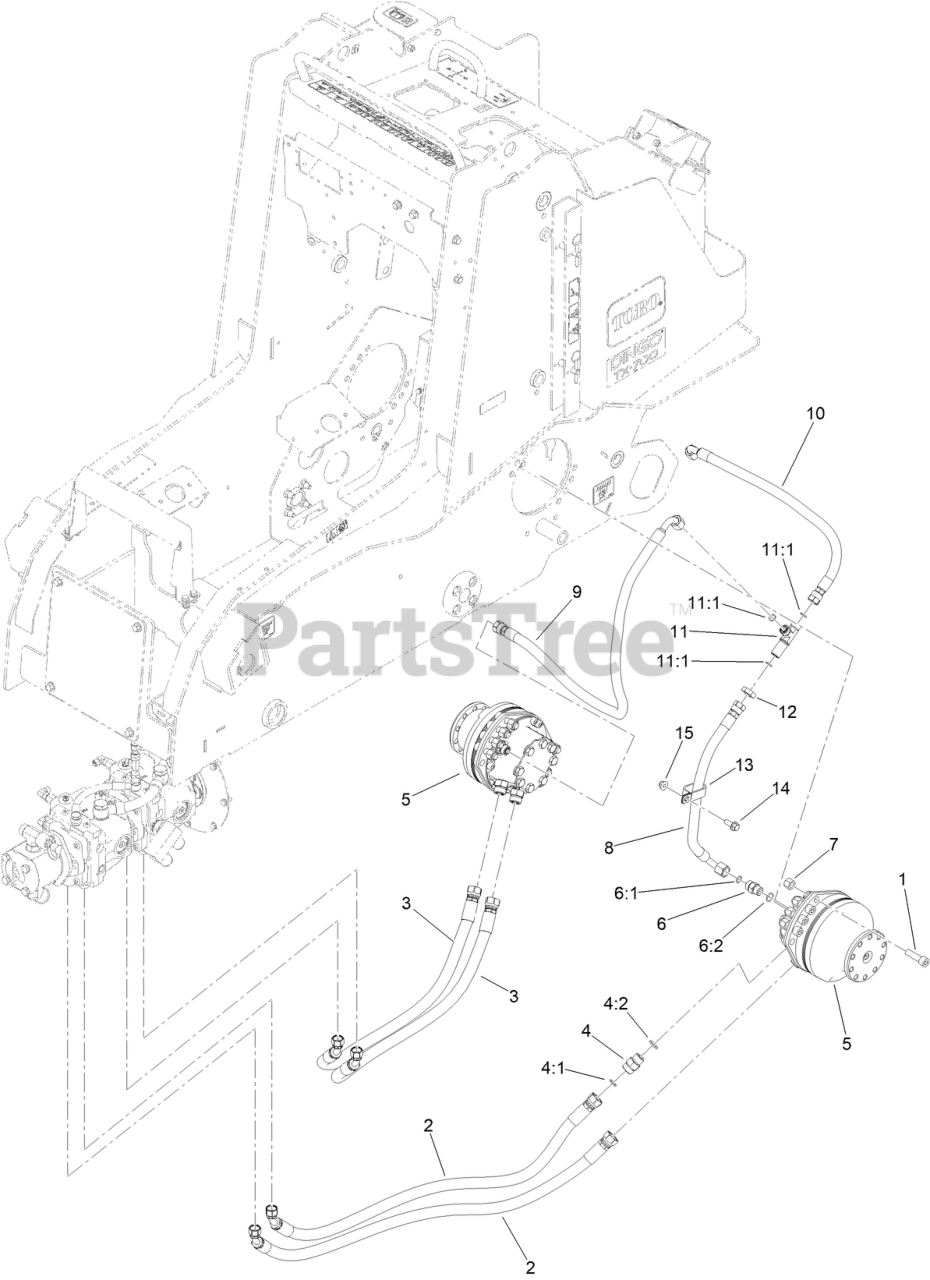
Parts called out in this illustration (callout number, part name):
1	NUT-LOCK, NI
2	HOSE ASM-HYD
3	HOSE ASM-HYD
4	FITTING-STRAIGHT
4:1	O-RING
4:2	O-RING
5	WHEELMOTOR ASM
6	FITTING-STRAIGHT
6:1	O-RING
6:2	O-RING
7	SCREW-HSH
8	HOSE ASM-HYD
9	HOSE ASM-HYD
10	HOSE ASM-HYD
11	FITTING-TEE
11:1	O-RING
12	NUT-BULKHEAD
13	CLAMP-R, DOUBLE
14	SCREW-HHF
15	NUT-HF, NI
